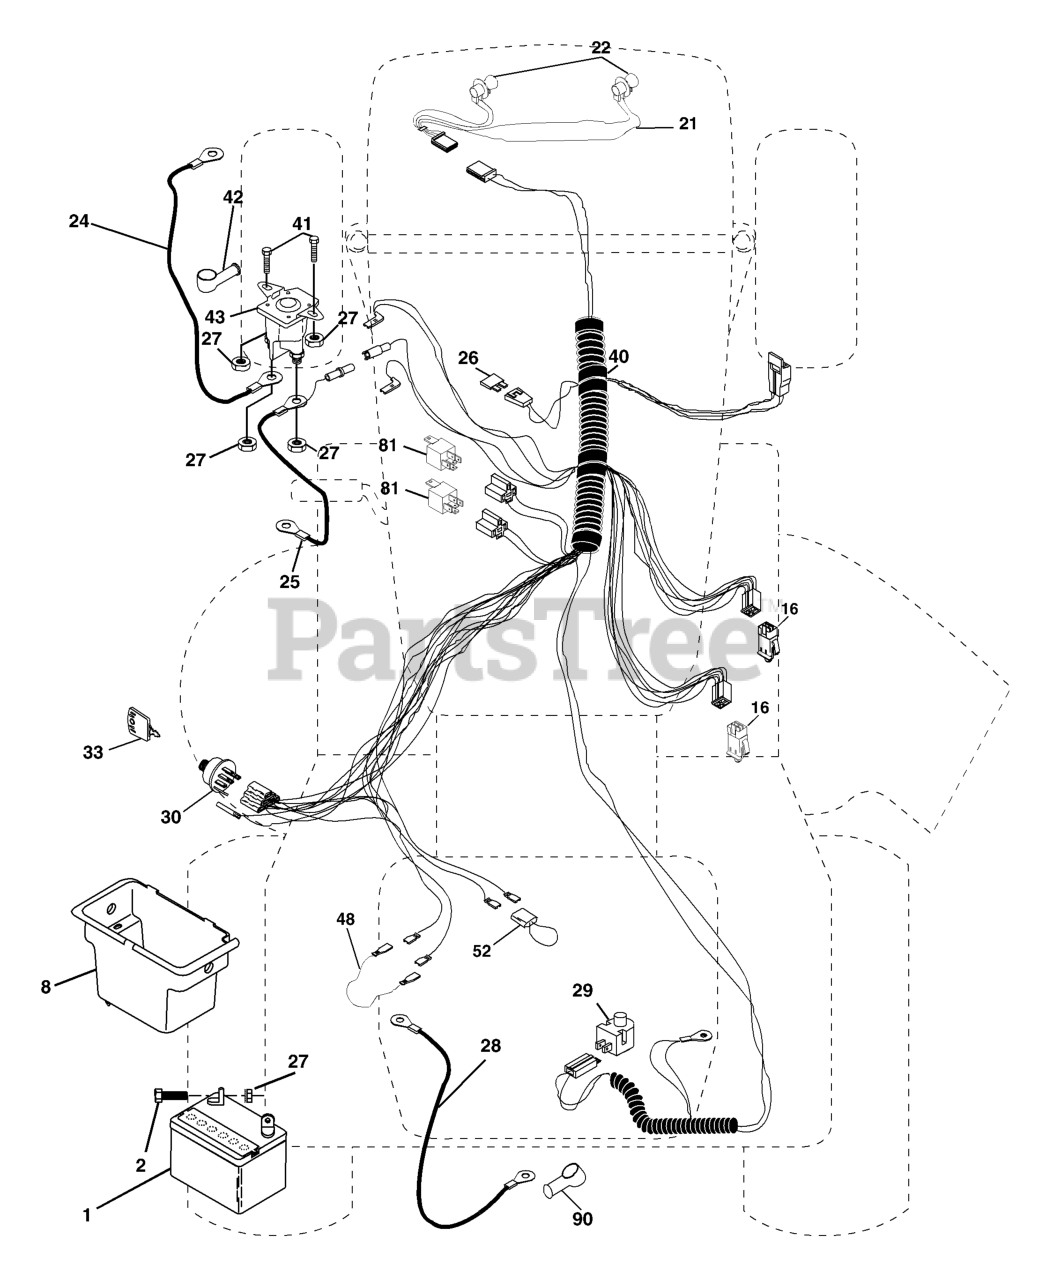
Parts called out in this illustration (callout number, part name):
1	Battery 12 Volt 28 AMP
2	BOLT.HEX.1/4.X.3/4.DICHROMATE
8	BOX.BATTERY.FENDER
16	INTERLOCK SWITCH
21	HARNESS.W/LIGHT SOCKET
24	BATTERY CABLE GT
25	CABLE BATTERY
26	FUSE 20AMP
27	NUT
28	CABLE T
29	PLUNGER SWITCH (COLOR:OLIVE)
30	IGNITION SWITCH
33	KEY MLD GEN DELTA
40	HARNESS IGN.
41	BOLT
42	TERMINAL COVER
43	SOLENOID
48	ADAPTER.AMMETER
52	WIRE PROTECTION LOOP
81	RELAY.ASSY.T
90	COVER TERMINAL
